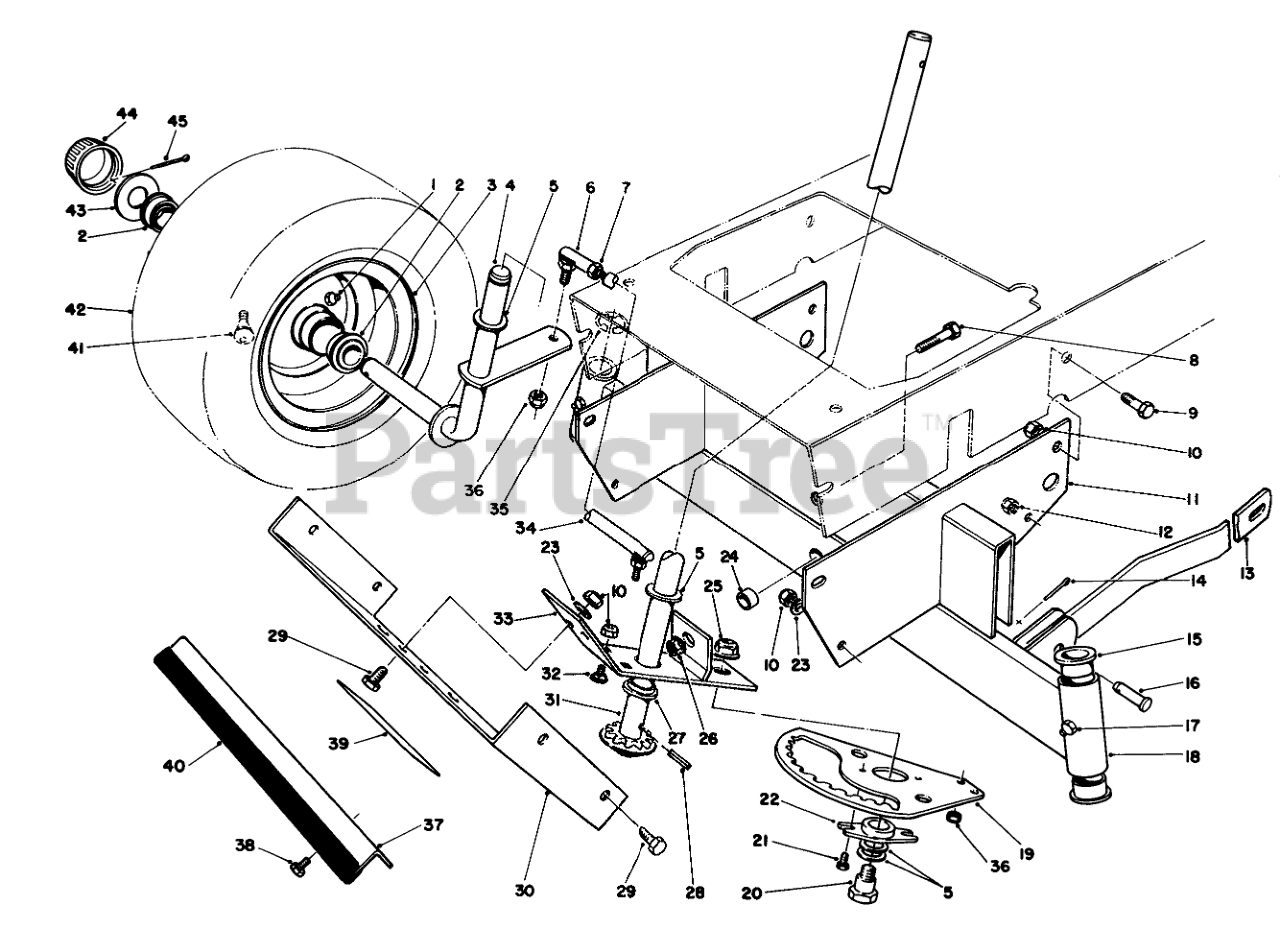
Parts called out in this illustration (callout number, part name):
1	FITTING-GREASE
2	Bearing
4	Spindle RH
5	WASHER-THRUST
6	JOINT-BALL
7	NUT-JAM
8	SCREW-HH
9	SCREW-HH
10	NUT-LOCK, NI
11	Support
12	NUT-LOCK, CONE
13	Arm-Suspension, Front
14	PIN-COTTER
15	BEARING-FLANGE
16	PIN-CLEVIS
17	GREASE FITTING
18	Axle-Front (Incl. Ref. #15 & 17)
19	STEERING RACK B
21	SCREW
22	BUSHING-SECTOR
23	WASHER-PLAIN
24	SPACER-AXLE, FRONT
25	NUT-HF
26	NUT-HF
27	BEARING-FLANGE
28	PIN-ROLL, SLOTTED
29	SCREW-HH
30	Cover-Front
31	STRG SHAFT WA
32	SCREW-CARR
33	Bracket-Steering Rack (Incl. Ref. #27)
34	Tie Rod-Steering (Incl. Ref. #35 & 36)
35	E-RING
36	NUT-LOCK
37	FRONT GUARD R
38	SCREW-HWHTF
39	Decal-Warning
40	TRIM-FRONT GUARD
41	STEM-VALVE
42	TIRE,PNEU.11X4.00X5
43	WASHER-PLAIN
44	CAP-HUB
45	PIN-COTTER
